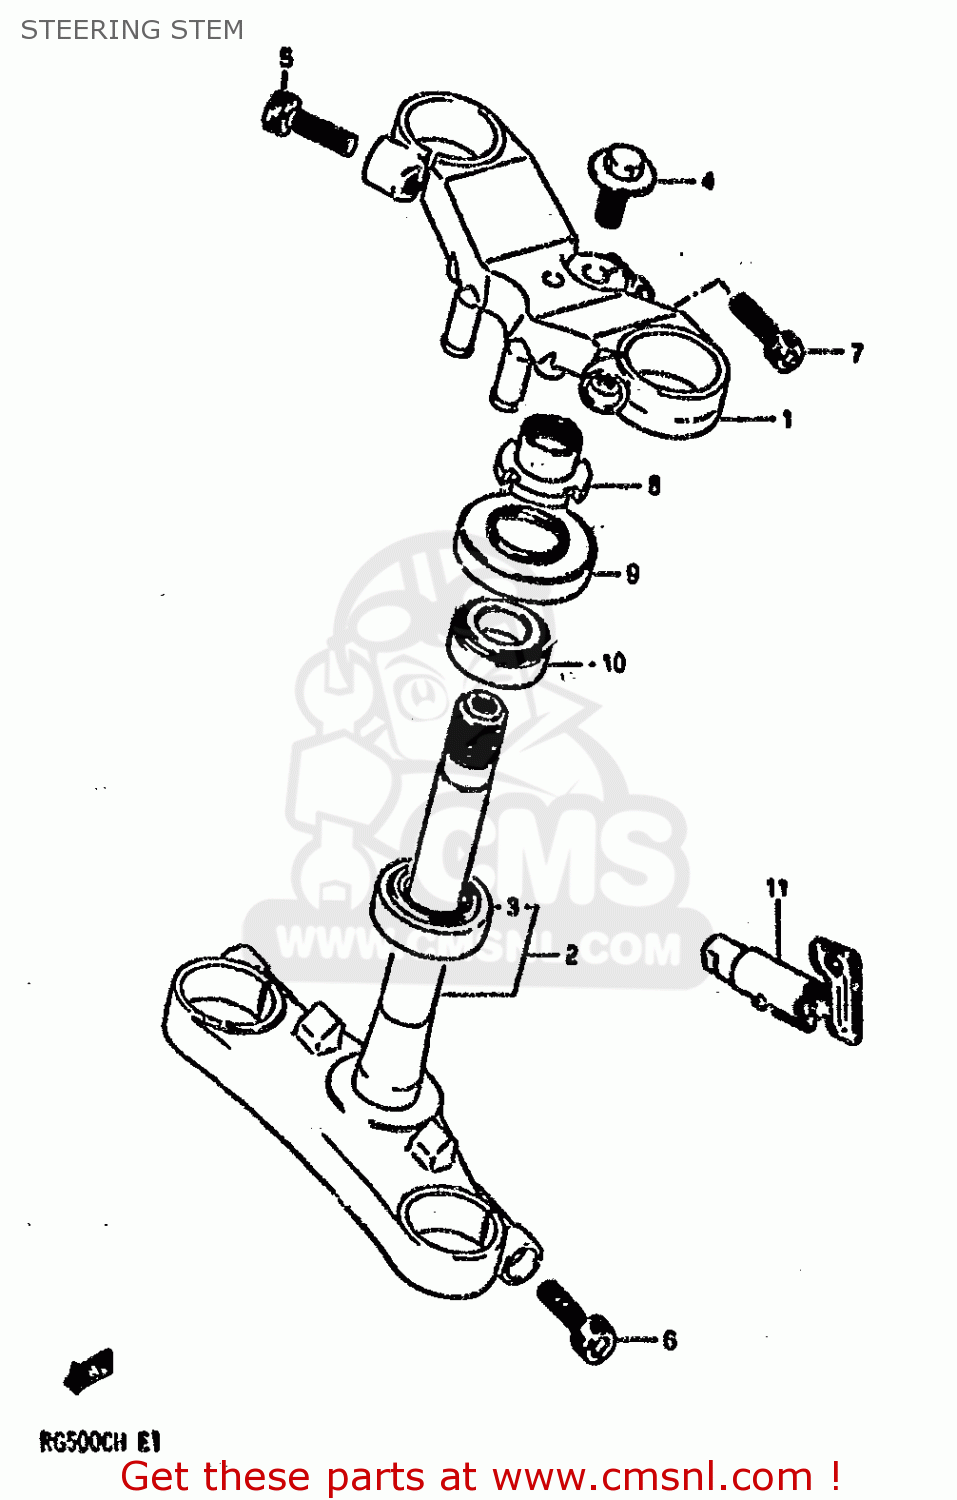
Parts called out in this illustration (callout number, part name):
1	HEAD,STEERING STEM (BLACK)
2	STEM,STEERING
3	BEARING
4	BOLT
5	BOLT
6	BOLT
7	BOLT, REAR (8X30)
8	NUT,STEERING STEM
9	SEAL OIL
10	TAPER,ROLLER BEARING
11	LOCK ASSEMBLY,STEERING (NEI
